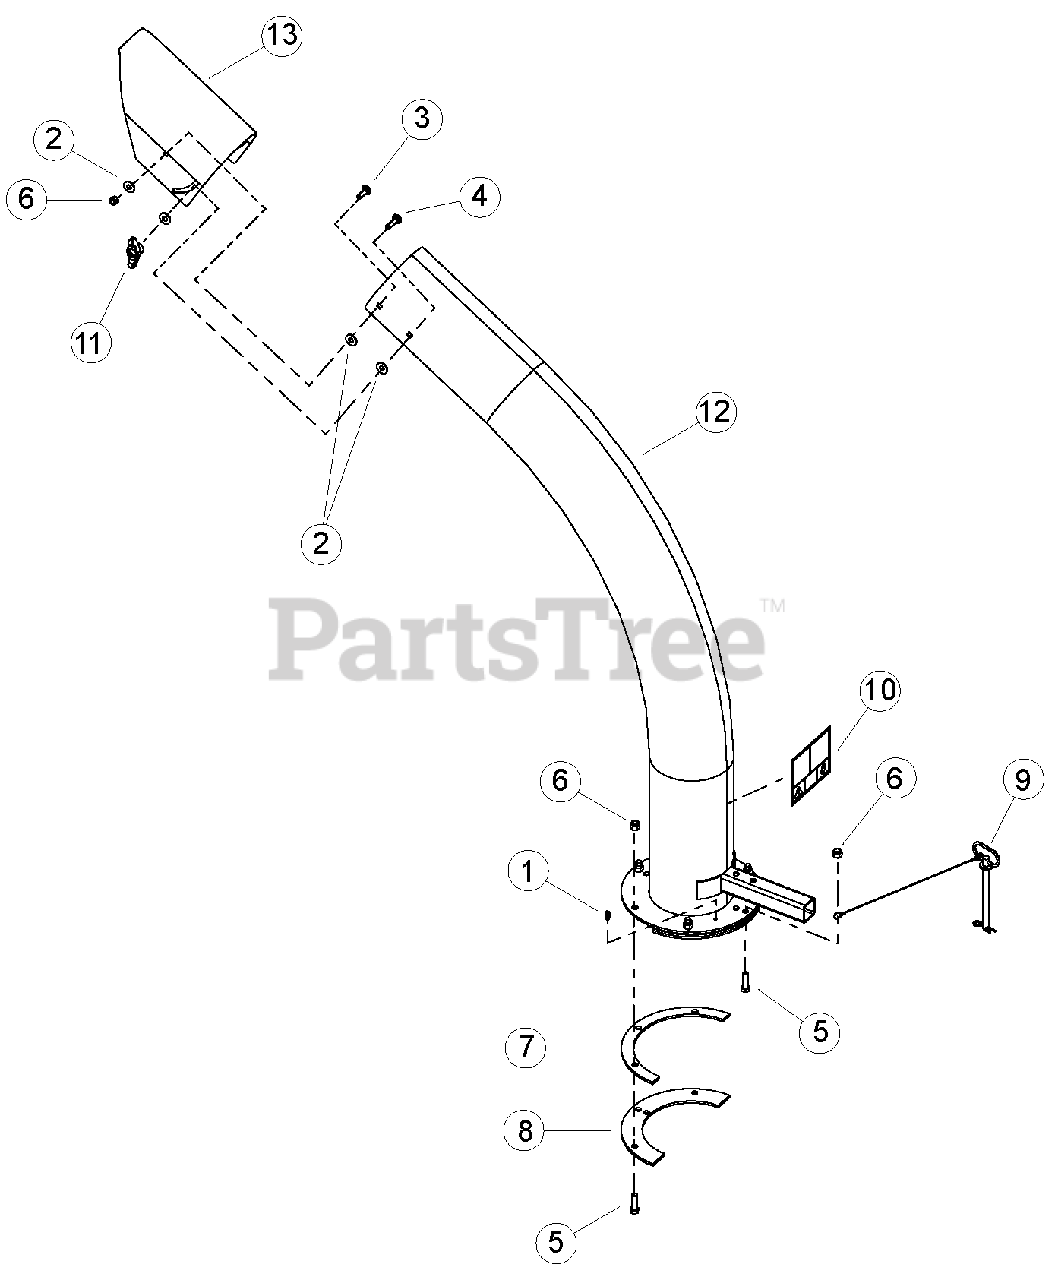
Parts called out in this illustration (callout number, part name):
1	FITTING, 1/4 SELF-TAP GREASE
2	WASHER, 3/8 FLAT ZP
3	BOLT, 3/8 X 1 CRG GR5 NC ZP
4	BOLT, 3/8 X 1-1/2 CRG GR5 NC ZP
5	BOLT, 3/8 X 1-1/4 HEX HD GR5 ZP
6	NUT, 3/8 NE NYLOCK ZP
7	RING, DISCHARGE SPACER
8	RING, DISCHARGE CLAMP
9	PIN, 3/8" X 4.25" DISCHARGE
10	DECAL, DISCHARGE DEBRIS & LOCK
11	KNOB, 3/8-16 UNC FEMALE TEE
12	ASSEMBLY, 8 INCH DISCHARGE SERVICE PART (CH800H)
13	CAP, 8 IN. DISCHARGE CHUTE
